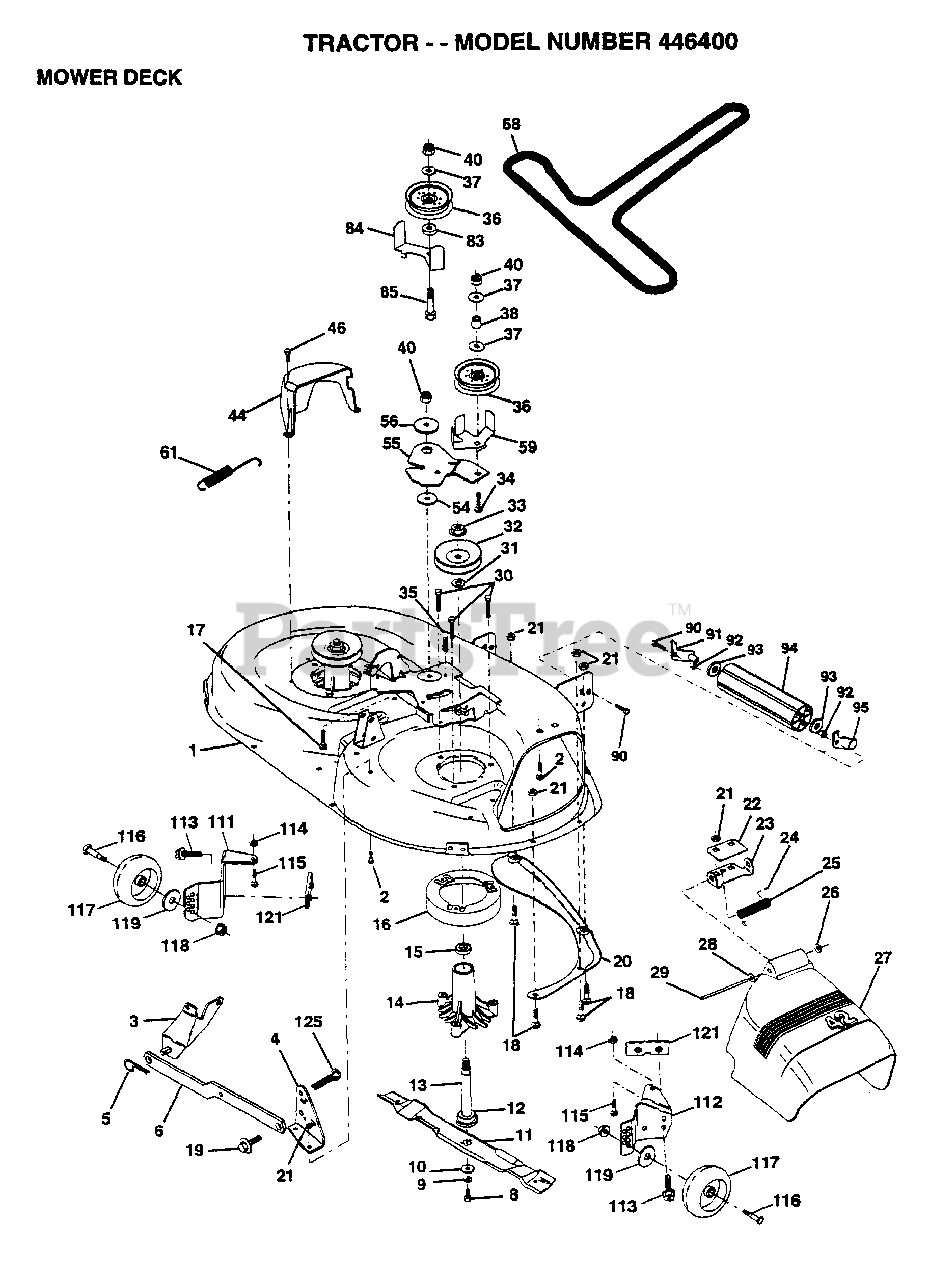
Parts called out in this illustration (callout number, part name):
1	DECK.WELD.42.
2	BOLT
3	BRKT ASM SWAY BAR
4	BRKT DECK SW BAR
8	BLADE BOLT
10	WASHER.HARD.BLADE
11	"BLADE.42"" HIPERF"
12	BEARING.BALL
14	HSG ASM MANDREL
15	BEARING
16	STRIPPER RND MWR
17	BOLT CARRIAGE
18	BOLT
19	BOLT SHD 5/16-18
22	STIFFENER BRKT
23	DEFLECTOR BRKT
24	CAP-SLEEVE LT
25	SPRING TORSION
26	NUT PUSH M
27	DEFLECTOR.SHIELD
28	WASHER
29	HINGE ROD
31	WASHER
34	BOLT
35	XMAS TREE FASTNER
36	FLAT IDLER PULLEY
37	WASHER
44	GUARD MAND LH BLK
46	SCREW.1/4-20X5/8
54	HARDENED WASHER
56	SPACER RETAINER
59	GUARD IDLER TUV
61	SPRING.EXTENSION
68	BELT.V.T-PATH
83	WASHER
85	BOLT
90	BOLT
92	NUT
93	WASHER
113	SCREW
116	BOLT.SHOULDER
117	WHEEL.GUAGE.MED.
118	LOCKNUT
119	WASHER
121	BRACKET.EXTRD.GWL
125	COTTER PIN
